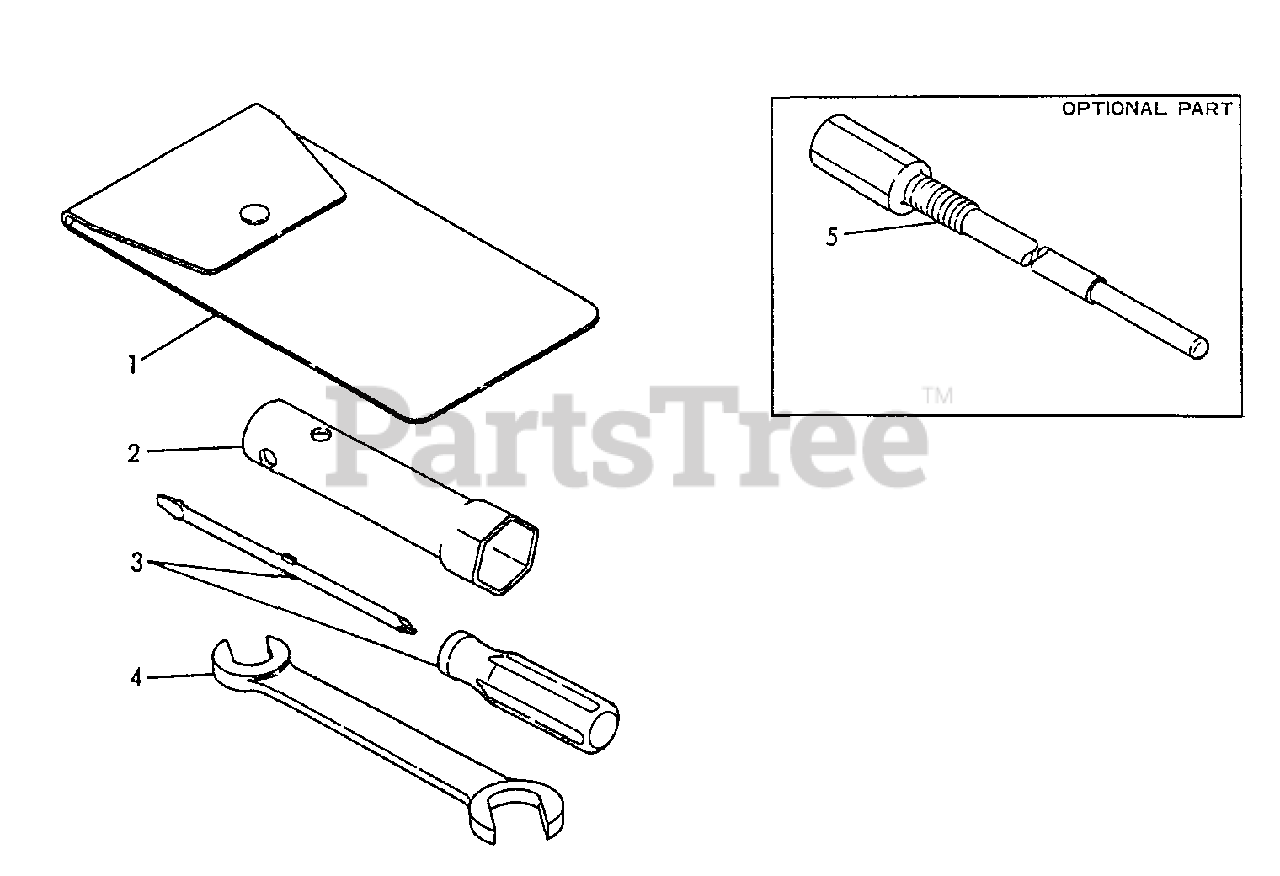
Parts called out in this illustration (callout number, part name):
1	BAG, TOOL
2	BOX SPANNER - 21
3	SCREWDRIVER
4	WRENCH 10×12
5	TOOL, ROTOR REMOVAL
